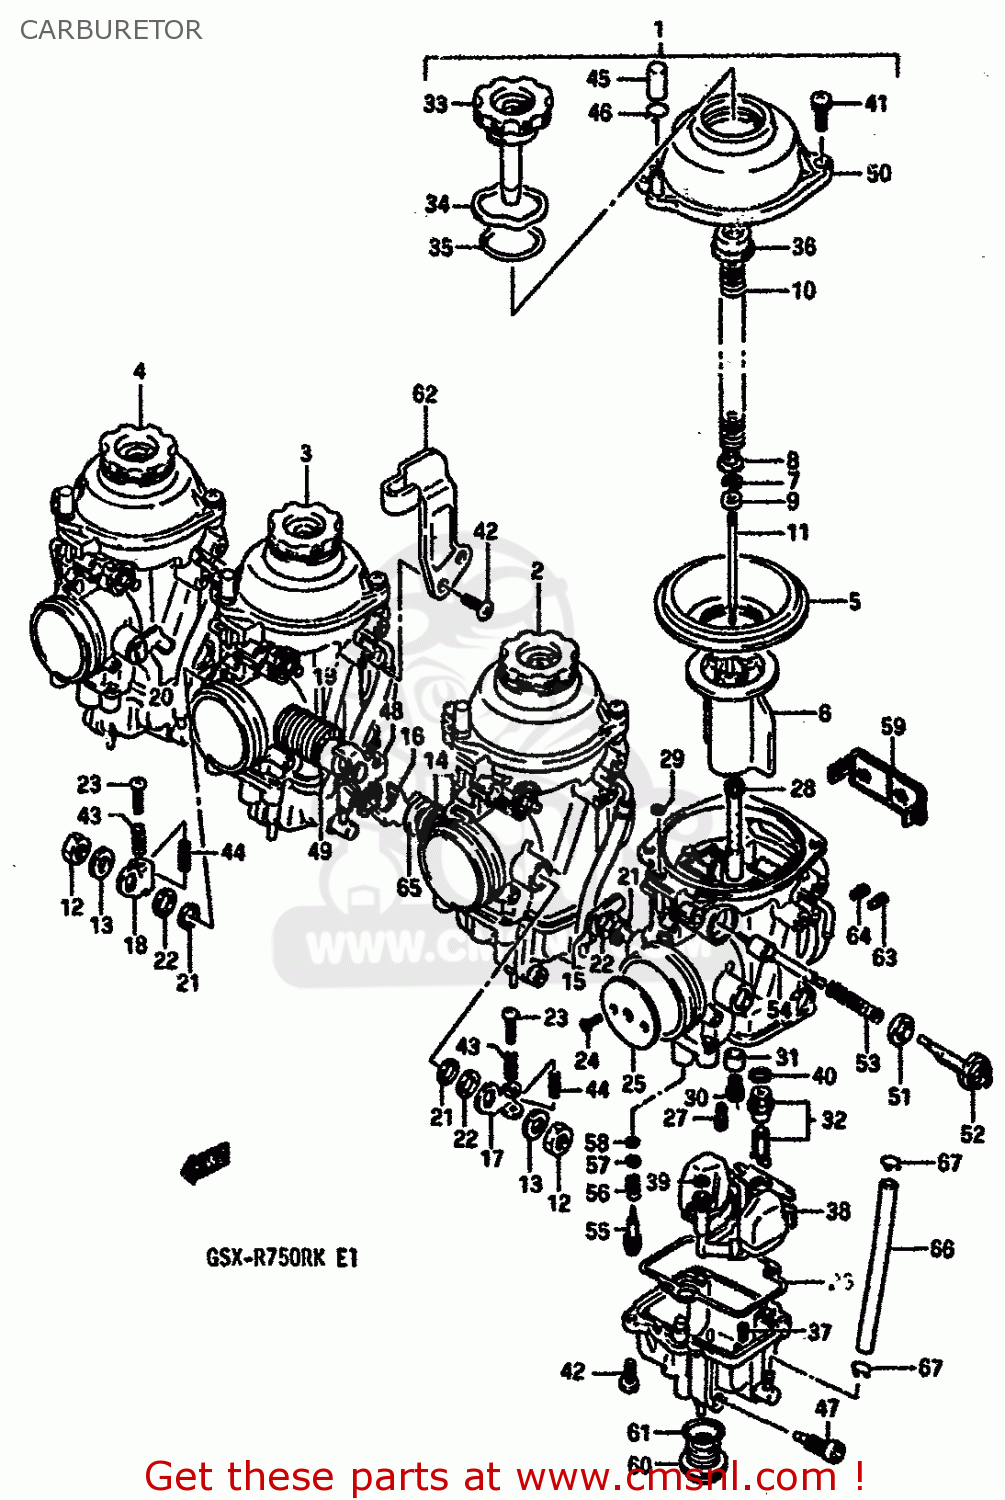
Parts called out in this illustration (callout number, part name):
1	CARBURETOR ASSY,LH
2	CARBURETOR ASSY,ML
3	CARBURETOR ASSY,MR
4	CARBURETOR ASSY,RH
5	DIAPHRAGM
6	VALVE,PISTON
7	CLIP,NEEDLE
8	RING
9	RING
10	SPRING
11	NEEDLE,JET (6ZEZ3-3)
12	NUT
13	WASHER,LOCK,8.
14	SPRING
15	SHAFT ASSY
16	SHAFT ASSY
17	LEVER
18	LEVER,THROTTLE
19	SPRING
20	SHAFT ASSY
21	SEAL
22	GASKET,THROTTLE SHAFT (NAS)
23	SCREW
24	SCREW
25	VALVE, THROTTLE (120)
26	GASKET,FLOAT CHAMBER (NAS)
27	JET,PILOT(37.5)
28	JET,NEEDLE (P-0)
29	O RING
30	JET,MAIN(115)
31	RING
32	VALVE ASSEMBLY,NEEDLE
33	CAP,TOP
34	LOCK WASHER
35	O RING
36	RING
37	PLUG
38	FLOAT ASSY
39	O RING
40	O-RING,NEEDLE VALVE
41	SCREW
42	SCREW
43	SPRING
44	SPRING
45	CAP
46	CLIP
47	PLUG
48	SHAFT ASSY
49	RING
50	COVER,DIAPHRAGM
51	CAP,STARTER
52	HOLDER,GUIDE
53	SPRING
54	PLUNGER ASSY
55	SCREW,PILOT
56	SPRING
57	WASHER
58	O RING,PILOT AIR SCREW
59	FILTER
60	SCREW,GUIDE
61	O RING,DRAIN PLUG
62	BRACKET
63	JET,MAIN AIR (0)
64	JET,AIR(1.0)
65	RING
66	HOSE
67	CLIP
